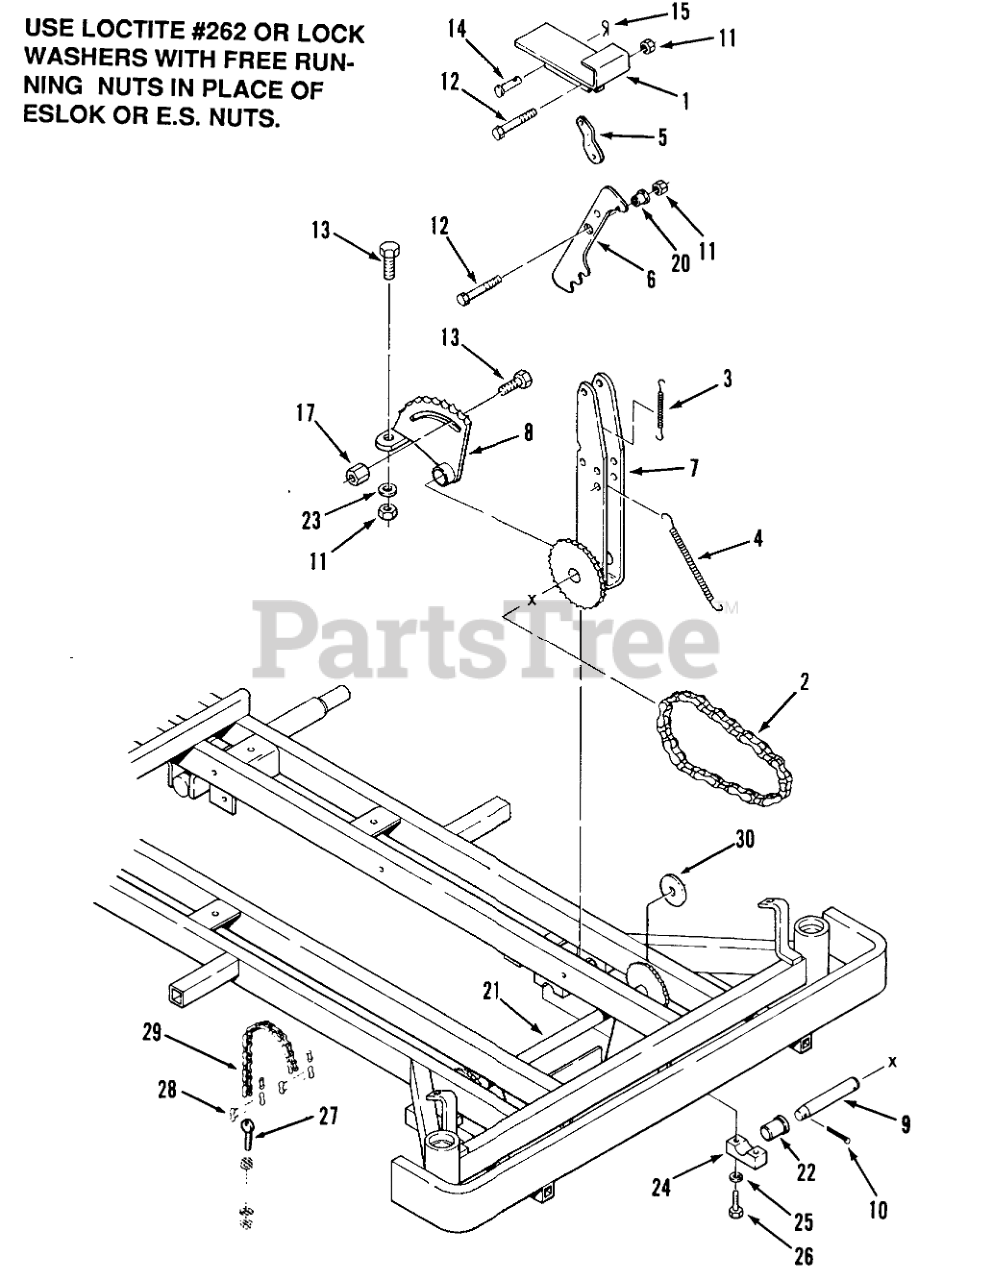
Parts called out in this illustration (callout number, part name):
1	PEDAL-FOOT 10218- B
2	CHAIN-FOOT PEDAL DR
3	SPG-NEUTRAL 20217-35
4	SPRING - EXTENSION
5	PIVOT-LINK B
6	LIFT-ARM PWL B
7	ASSY-LVR ARM 1022 B
8	HEIGHT CONTROL SP B
9	PIN-PEDAL
10	Cotter Pin
11	Nut
12	HHCS
13	Bolt
14	Pin-Clevis
15	Cotter Pin
17	HEX-STOP NUT N-140
20	BUSHING-PDL
21	ASM-Sprocket
22	BEARING-FLANGED
23	WASHER 5/16 SAE
24	Cross Shaft Clamp (included w/ frame)
25	Lockwasher 3/8 (included w/ frame)
26	Bolt 3/8-16 x 1-1/4 (included w/ frame)
27	EYE-BOLT 3/8-16X2.50
28	MASTER LINK CHAIN
29	CHAIN-DECK LIFT
30	Washer
